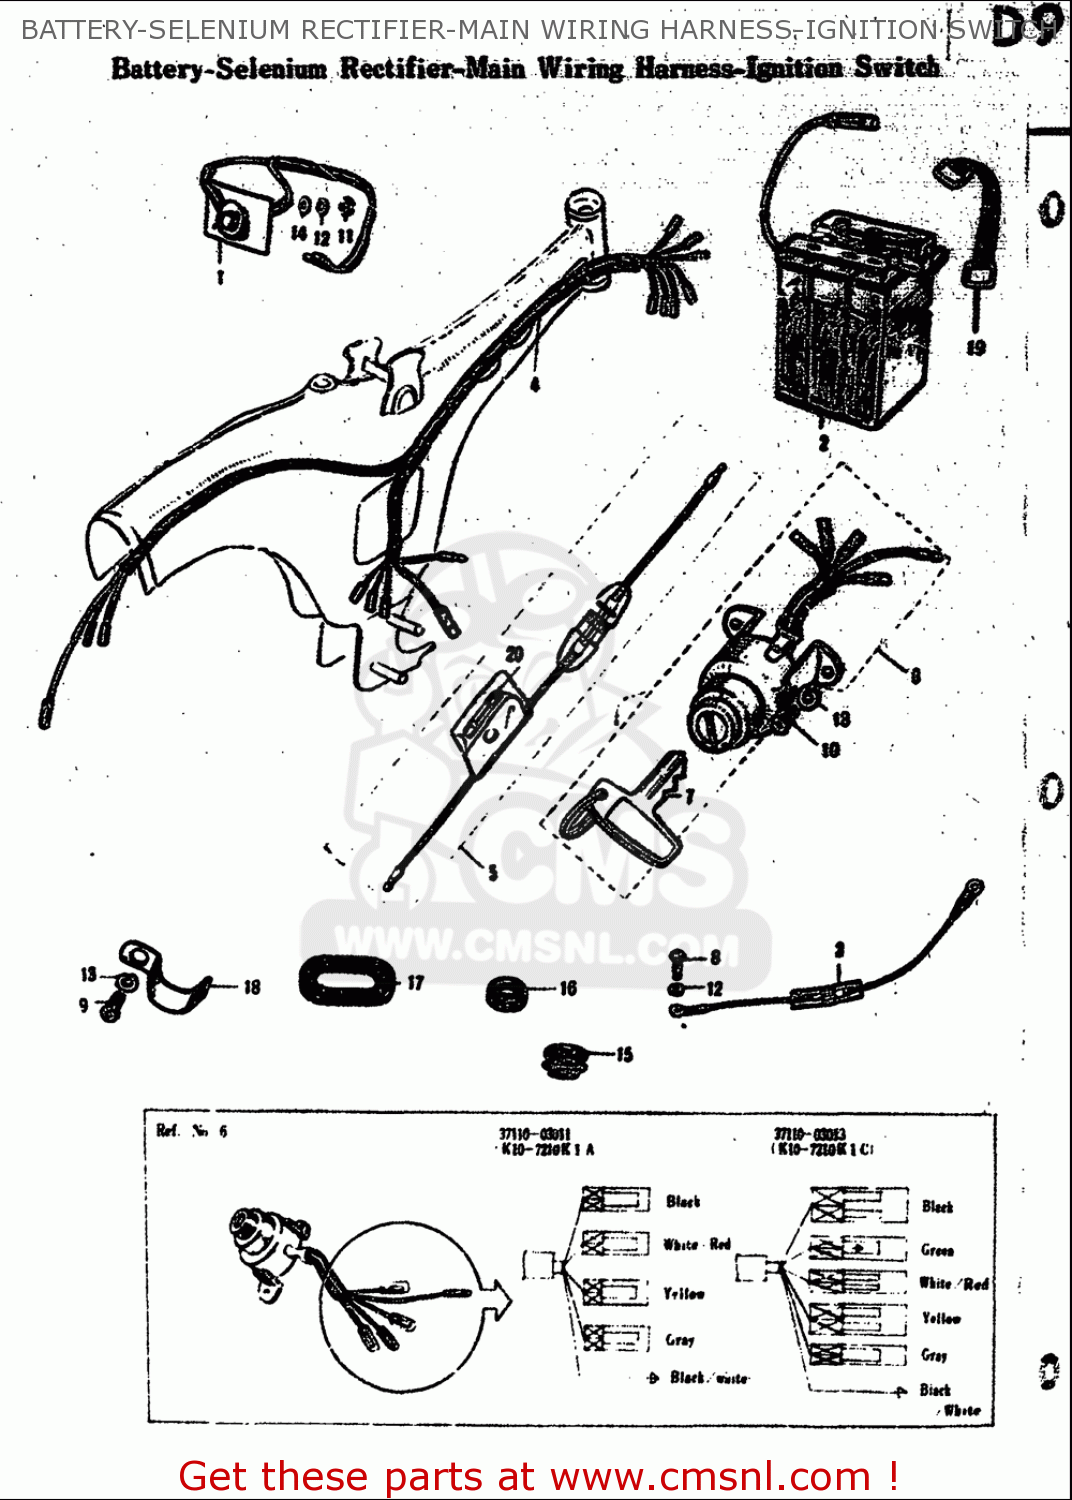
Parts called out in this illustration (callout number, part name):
1	RECTIFIER ASSY
2	BATTERY ASSY(6N4-2A4.2AH)
10	SCREW
11	NUT
12	WASHER,LOCK
13	WASHER,LOCK
14	WASHER
16	GROMMET
19	BAND
